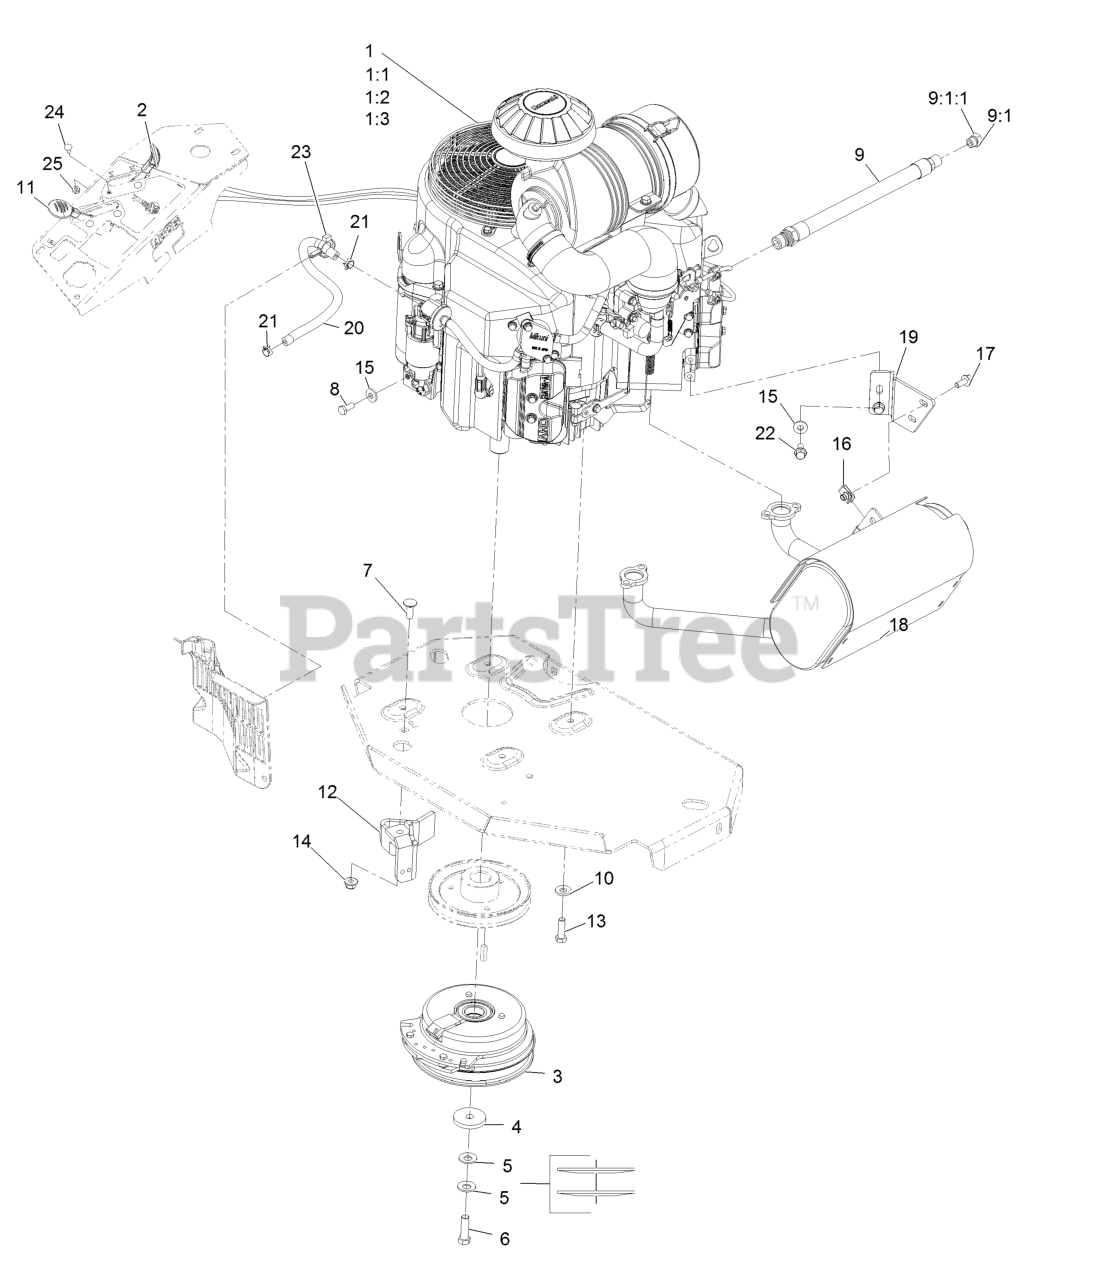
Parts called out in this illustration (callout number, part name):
1:1	Kawasaki 49065-2078 Engine Oil Filter
1:2	Kawasaki 11013-7044 Engine Air Filter
1:3	Kawasaki 11013-7045 Safety Filter
2	ASM, Choke Cable
3	Clutch Kit
4	Washer-Clutch
5	Washer-Spring Disc 7/16
6	Screw-HH 7/16-20 X 1 1/2 W/Loctite
7	Bolt-Carriage 3/8-16 X 1
8	Screw-HH M8-1.25 X 20Mm
9	Asm-Hose Oil Drain W/Plug
9:1	Plug-W/O-Ring
9:1:1	O-Ring
10	Washer-Spring Disc 3/8
11	ASM,Throttle Cable
12	Clutch-Anchor
13	Screw-HH 3/8-16 X 1 1/4
14	Nut-Nyloc 3/8-16 Flg
15	Washer-Spring Disc 5/16
17	Screw-HH Flg 5/16-18 X 3/4
18	Muffler
19	Bracket-Muffler
20	Hose-Fuel Line 15"
21	Clamp-Hose
22	Screw-HH M8-1.25 X 20Mm
23	Clamp-Hose
24	Bolt-Carriage #10-24 X 1/2
25	Nut-Nyloc #10-24
